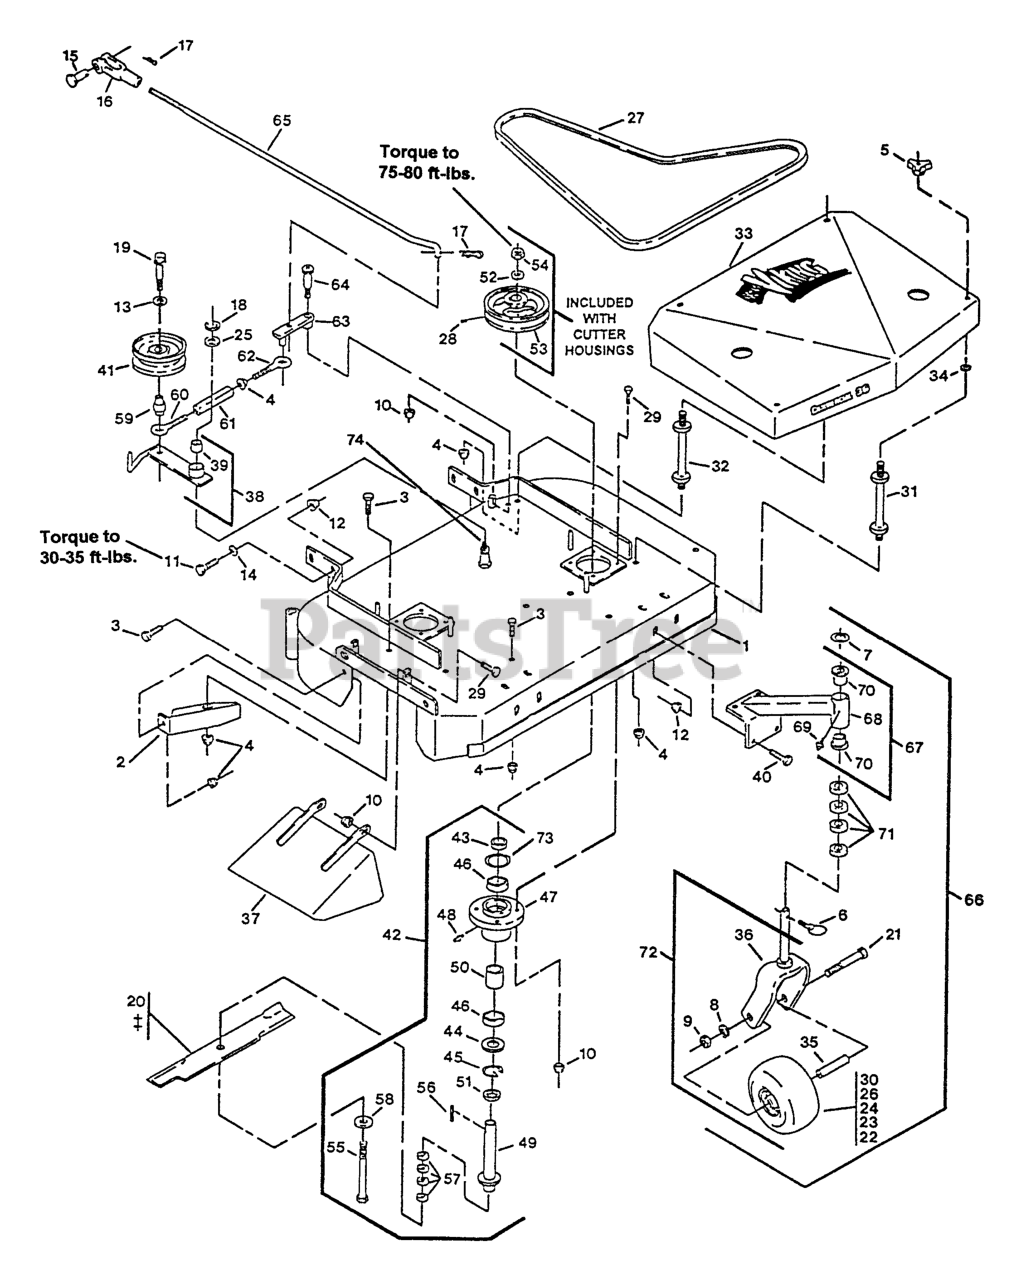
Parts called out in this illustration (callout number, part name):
2	BAFFLE-DOGLEG
5	KNOB-3 PRONG
7	WASHER-FLAT
15	PIN-CLEVIS
16	YOKE-ADJUSTABLE
17	PIN-COTTER
22	BUSHING
23	BEARING
25	WASHER-SPINDLE
27	BELT,BLADE DRIVE 36
28	SCREW-SET
31	STUD-SHIELD, BELT (SHORT)
32	STUD-SHIELD, BELT (LONG)
37	Chute
39	BEARING,POWDERED METAL
42	ASM,HOUSING CUTTER
44	SEAL,DUST
45	RING,SNAP WLDS N5000-244
46	BEARING,HD SPINDLE
47	HOUSING,CUTTER
50	SPACER,BRG/BRG
51	SPACER,BEARING &SPINDLE
52	WASHER-RETAINER, SHEAVE
55	SCREW-CAP, HH
58	WASHER-SPRING
59	BUSHING-ENGAGEMENT
60	EYEBOLT-THREAD, LH
61	BODY-TURNBUCKLE
62	EYEBOLT-THREAD, RH
64	BOLT,SHLDR KSKH
66	CASTER/MOUNT ASM
67	SUPPORT ASM
70	BEARING-FLANGED
71	SPACER-CASTER
